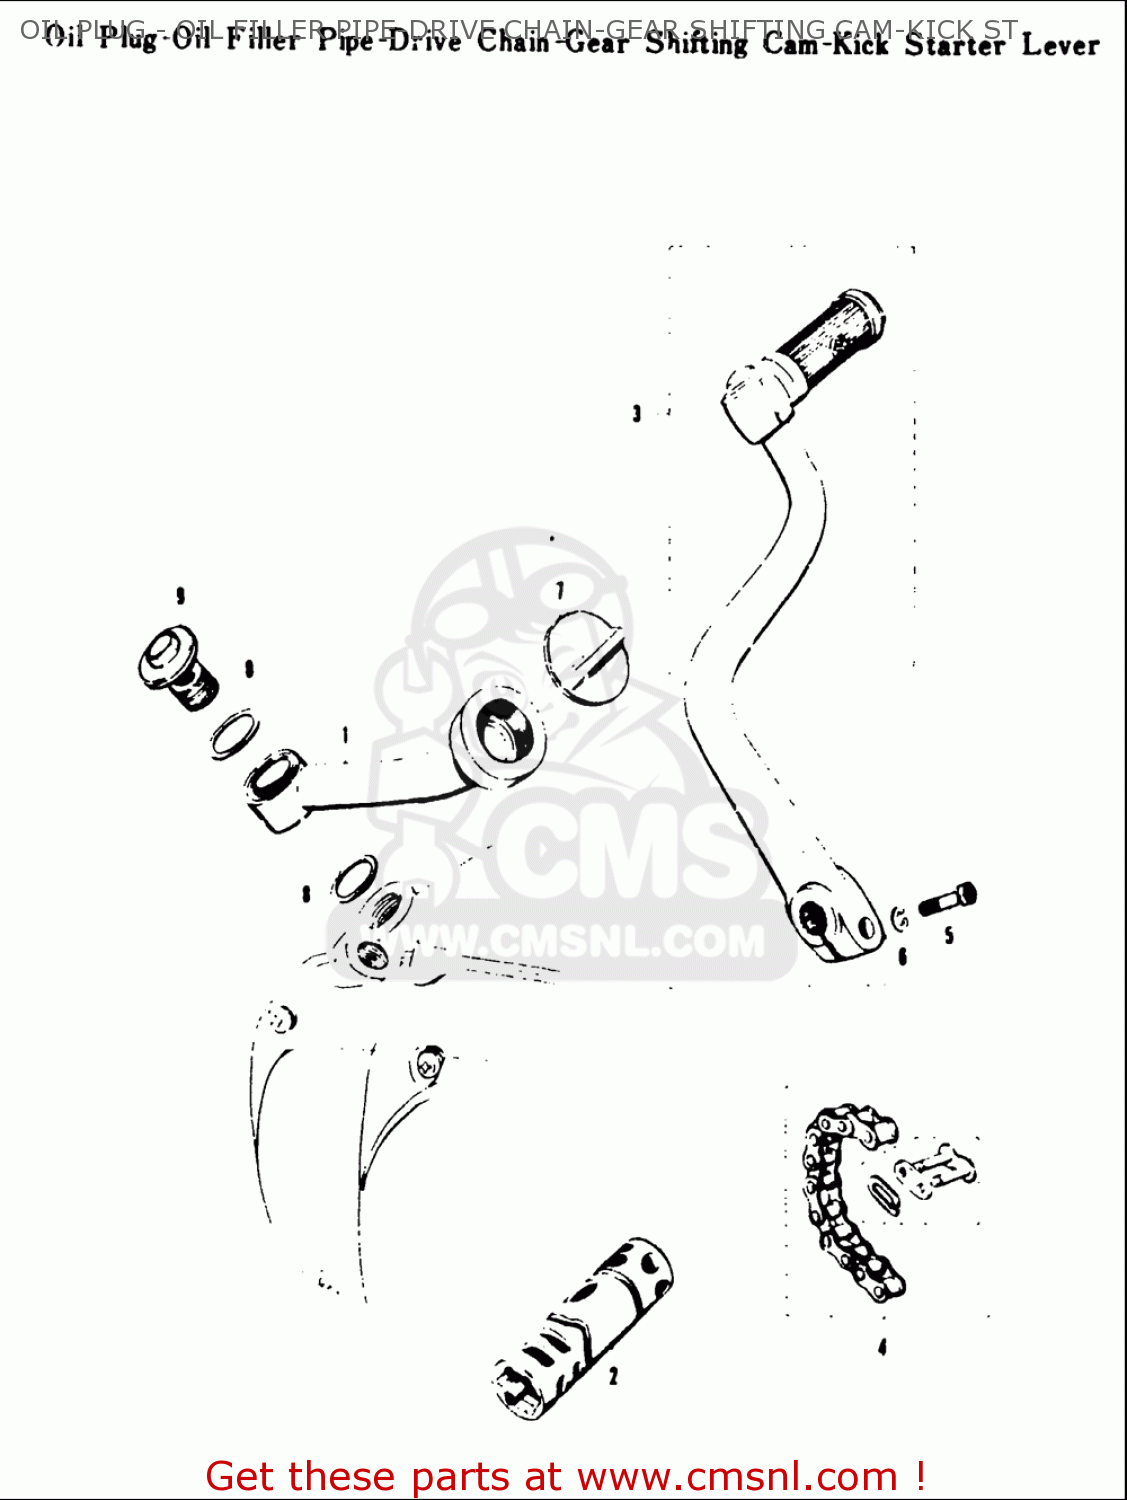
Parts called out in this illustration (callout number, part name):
4	CHAIN,DRIVE #525TR-10
5	BOLT
6	WASHER,LOCK
7	PLUG SET
8	O RING(D:2.4,ID:21.8)
